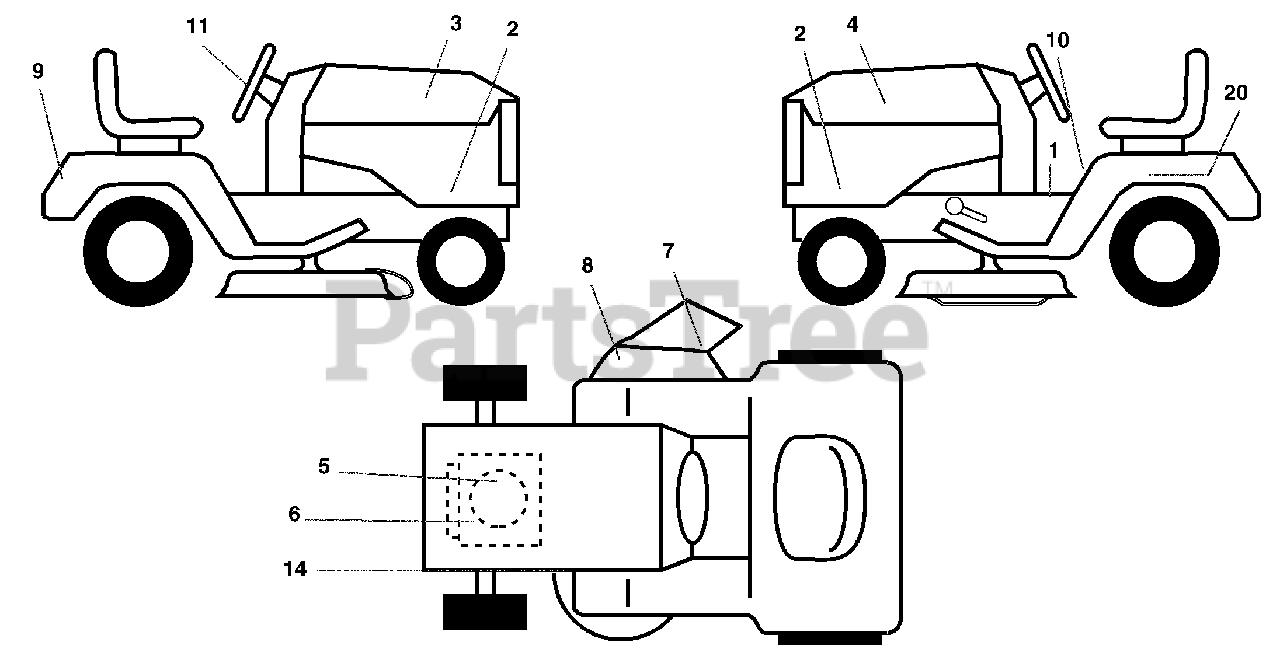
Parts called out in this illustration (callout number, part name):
1	Decal Oper. Step Thru Eng/Fr
2	Decal Side Panel
3	Decal Hood RH
4	Decal Hood LH
5	Decal Hood Cust.
6	Decal Engine
7	Decal Deck B 42
8	Decal Warning
9	Decal Fender Husq
10	Decal Fender Danger Eng/Fr
11	Decal SW Husq Prem
14	Decal V-Belt Schematic
20	Decal Bat Dan/Psn
